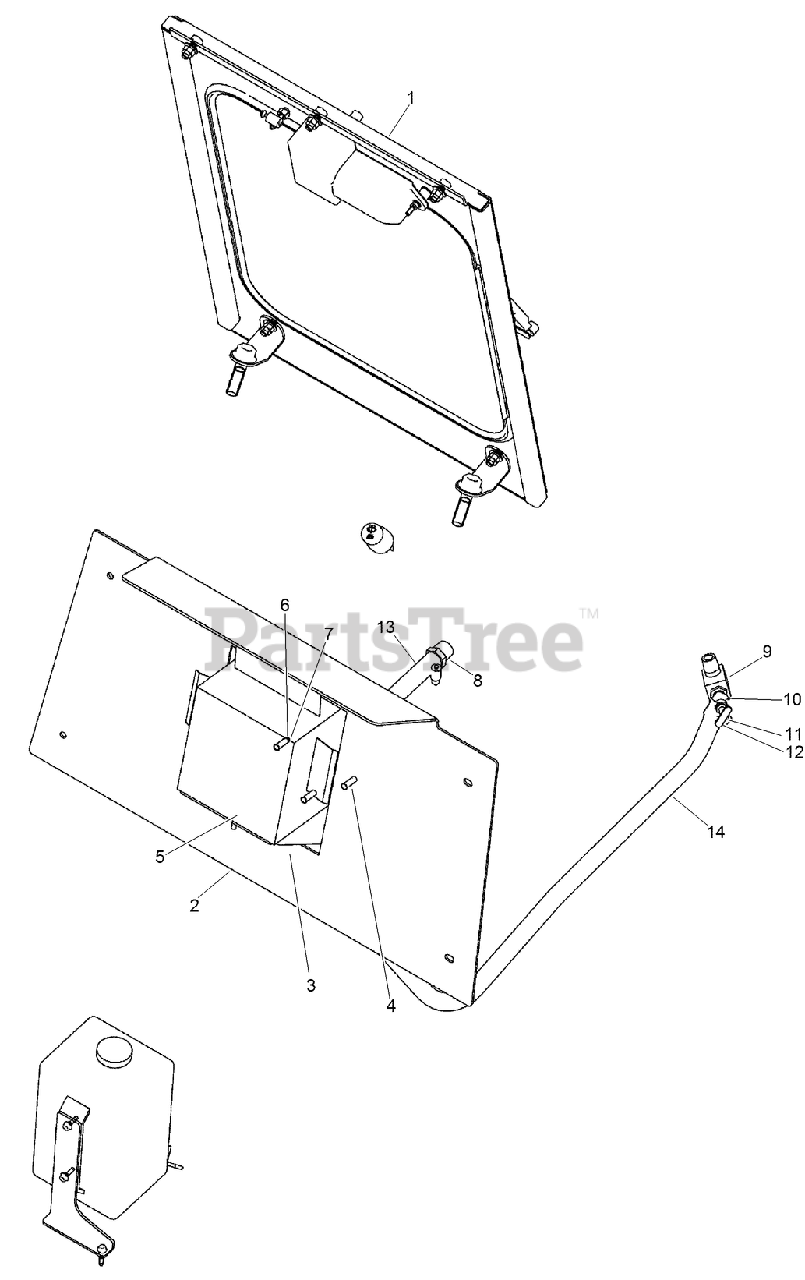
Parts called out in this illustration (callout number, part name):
1	KIT - Front Windshield
2	PLATE - Kick Panel
3	PLATE - Heater Mnt Bracket
4	HEATER
5	NUT - Hex .250 - 20 GR5 ZND
6	SCREW-HHF
7	NUT-FLANGE, NYLOCK
8	STEM - Str Bead Hose 5/8 ID x 3/4 NPTF
9	ELBOW - 90, 1/2 NPTF Male/Female, MI Blk
10	BUSHING - Hex Reducer Pipe 1/2 x 3/8 Galv
11	VALVE - Shut-Off
12	CLAMP - Hose, Type F #20
13	HOSE - Silicon
14	HOSE - Silicon
